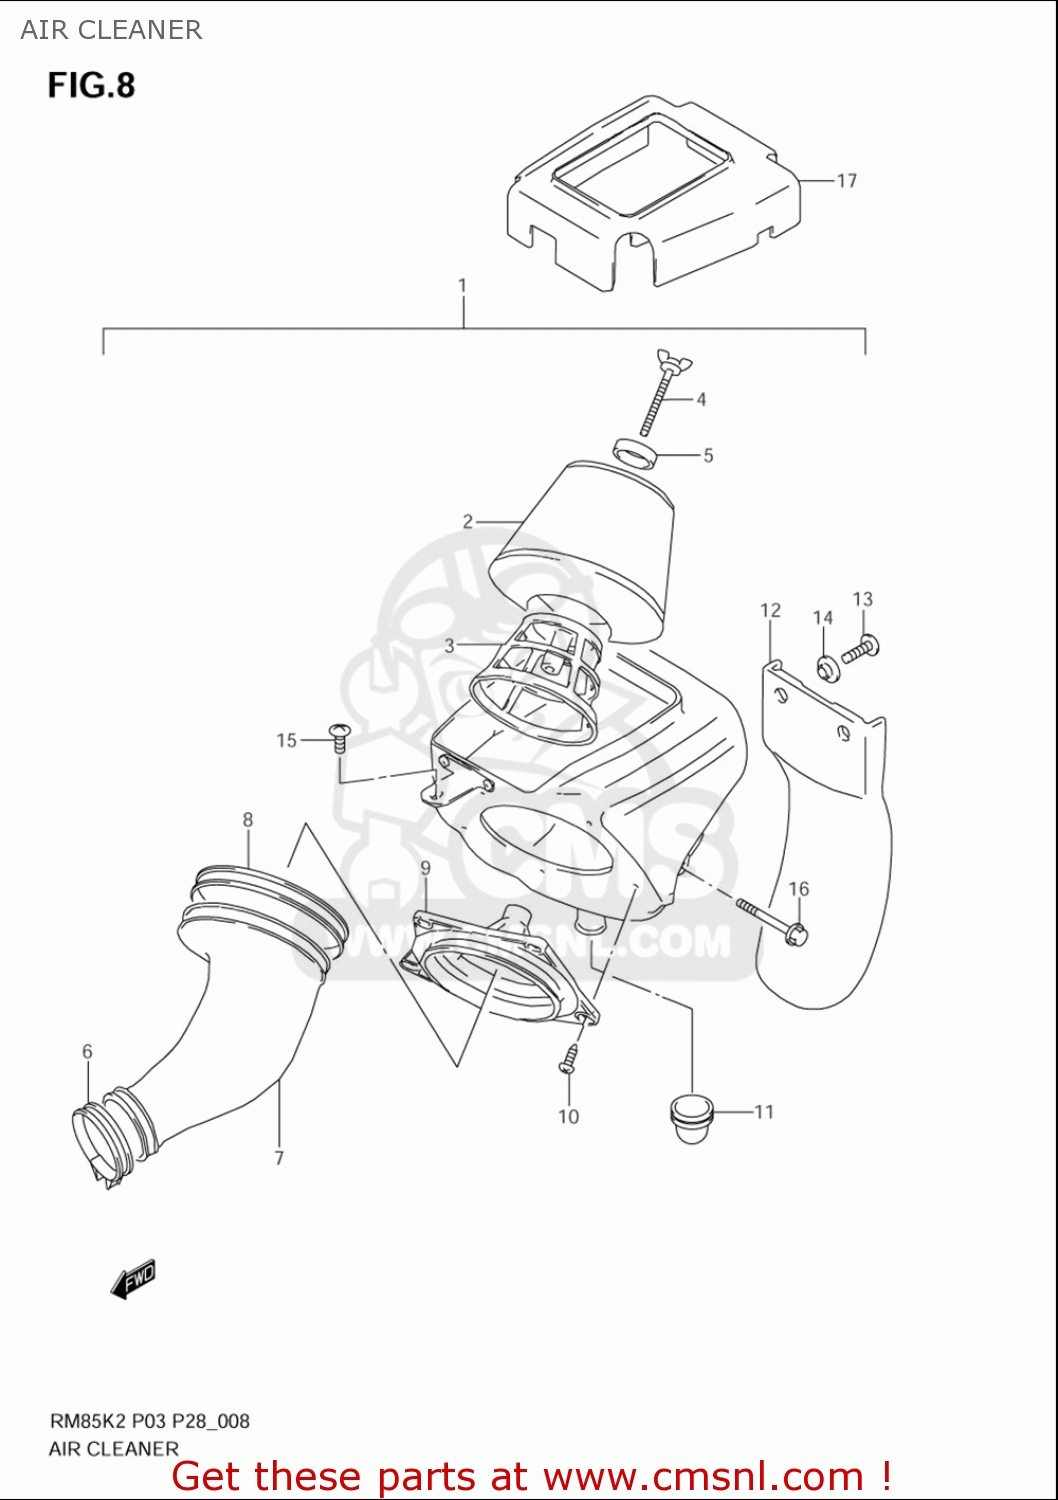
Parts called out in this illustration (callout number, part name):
1	CLEANER ASSY,AIR
2	FILTER ASSY
3	HOLDER
4	BOLT,WING
5	WASHER,AIR CLEANER
6	CLAMP
7	TUBE,OUTLET
8	CLAMP
9	BASE,FILTER
10	SCREW
11	HOSE,AIR CLEANER DRAIN
12	GUARD,MUD
13	SCREW
14	COLLAR
15	SCREW
16	BOLT(6X45)
17	MUDGUARD,B
